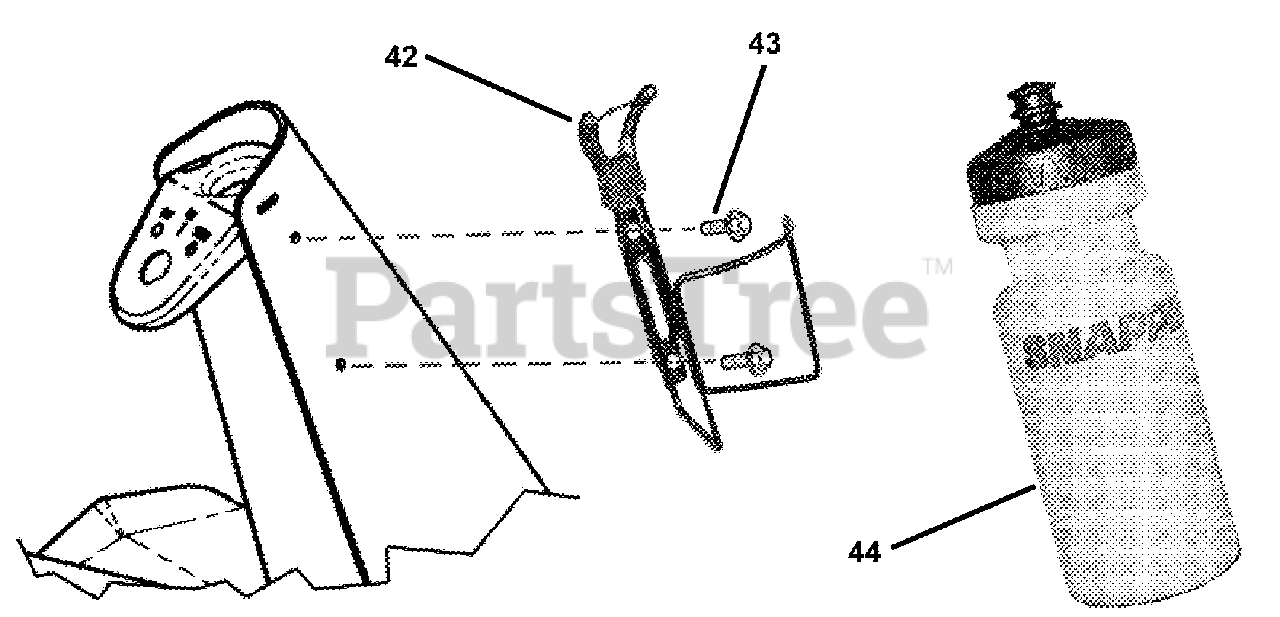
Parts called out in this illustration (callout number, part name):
42	HOLDER, Wire- Bottle
43	SCREW, #10-24 x 1/2" Hex Washer Self-Tap (Torx)
44	BOTTLE, Water
